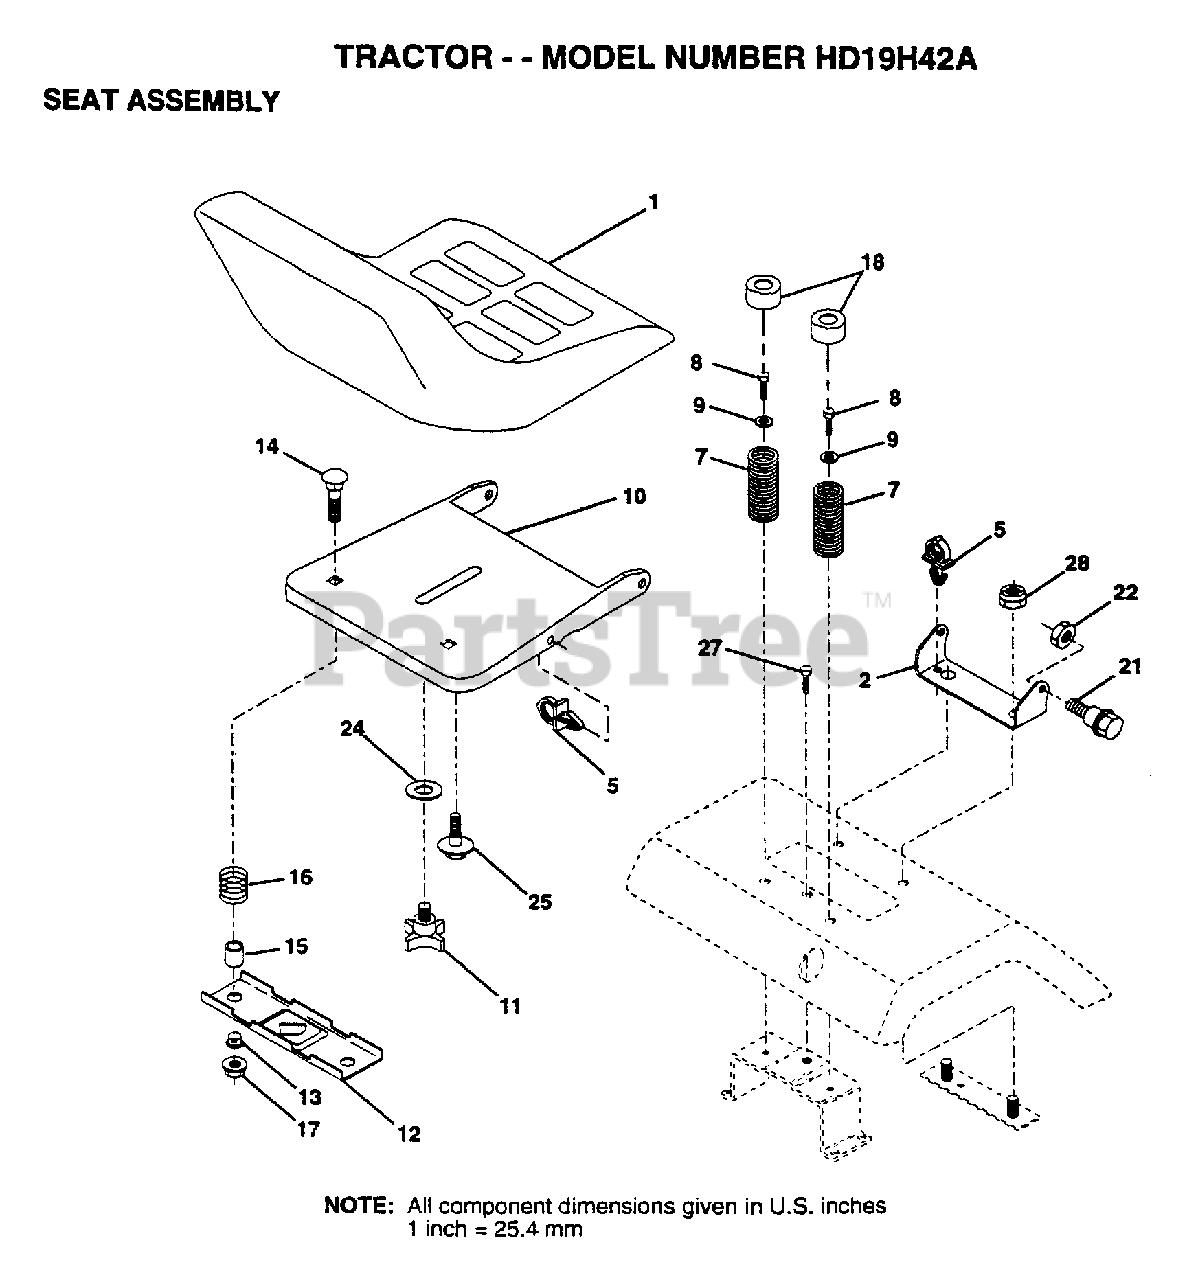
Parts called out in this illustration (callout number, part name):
1	SEAT.2500/1516.BK
2	BRACKET PVT SEAT
5	CLIP.PUSH-IN.HING
7	SPRING COMPRESSIO
8	SCREW LT
9	WASHER
11	"KNOB 1/2"" YT"
12	BRKT SWITCH
13	BUSHING
15	SPACER SPLIT
16	SPRING COMPRESSED
18	CAP SPRING
21	BOLT.SHLD.5/16-18
24	WASHER
25	"BOLT,SHOULDER"
27	SCREW LT
